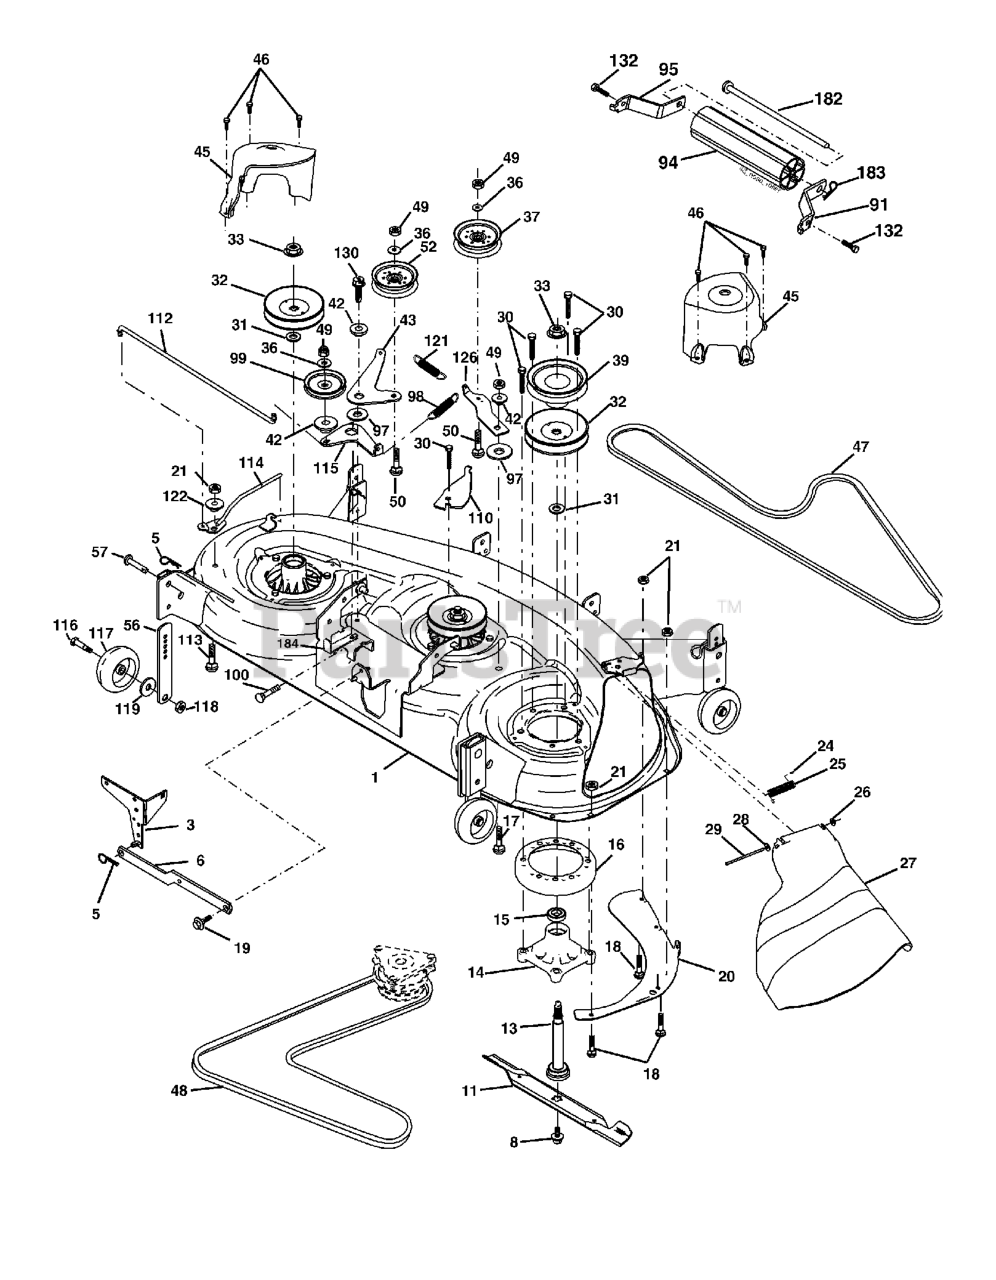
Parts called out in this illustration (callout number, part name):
1	DECK WELDMENT
3	BRACKET ASM.
5	RETAINER-SPRNG RB
6	BAR SWAY DECK
8	BOLT 7/16 ASM BLADE
11	48" HI-LIFT BLADE
13	SHAFT ASM W/LOWER BEARING
14	HOUSING, MANDREL 48"
15	BEARING
16	STRIPPER.MANDREL.ROUND.BLACK
17	BOLT
18	BOLT
19	BOLT SHD 5/16-18
20	BAFFLE, VORTEX MWR
21	LOCKNUT
24	CAP-SLEEVE LT
25	SPRING, TORSION
26	NUT PUSH M
27	DEFLECTOR SUBS TO 532 180655
28	Washer 11/32 x 5/8 x 16 Ga SD
29	ROD.HINGE
30	SCREW, WASHER HEAD
31	WASHER.SPACER.MANDREL
32	PULLEY, MANDREL
33	NUT, FLG TOPLOCK 9/16"
36	WASHER
37	PULLEY.IDLER.FLAT
39	PULLEY.DRIVEN.DECK.48'
42	SPACER.RETAINER.MOWER
43	ARM, IDLER SECONDARY
45	COVER.MANDREL.DECK.48"
46	SCREW.1/4-20X5/8
47	V-BELT, 48"SECONDARY
48	V-BELT PRIMARY 48"
49	LOCKNUT
50	BOLT.3/8-16X1.50
52	PULLEY.IDLER.FLAT.46.PR.DR.
56	BAR.ADJUST.WHEEL.ANTI.SCALP.BL
57	RIVET.PIN.HEAD.YELLOW.
91	BRKT.NOSEROLLER.RH.48"
94	NOSE ROLLER 48"
95	BRKT.NOSEROLLER.LH.48"
97	WASHER
98	SPRING PRIMARY DRIVE
99	IDLER PULLEY
100	BOLT
110	ARM, SPRING SECONDARY
112	LEVER, TENSION RELIEF LINK
113	BOLT.CARR.SQNK.5/16-18UNC.X3/4
114	LEVER ASM, TENSION RELIEF
115	ARM, SPRING TENSION RELIEF
116	SHOULDER BOLT
117	WHEEL GAGE DONUT
118	LOCKNUT
119	WASHER.5/16.FLAT.STE.STD.
121	SPRING.DRIVE.SECONDARY.48".DEC
122	BUSHING, PIVOT TENSION RELIEF
126	ARM, IDLER PRIMARY DECK
130	SCREW 3/8-16X1
132	SCREW, 3/8-16X3/4
182	ROD.ROLLER.NOSE.NARROW.48"
183	SPRING RETAINER
184	KEEPER BELT IDLER PLATED
